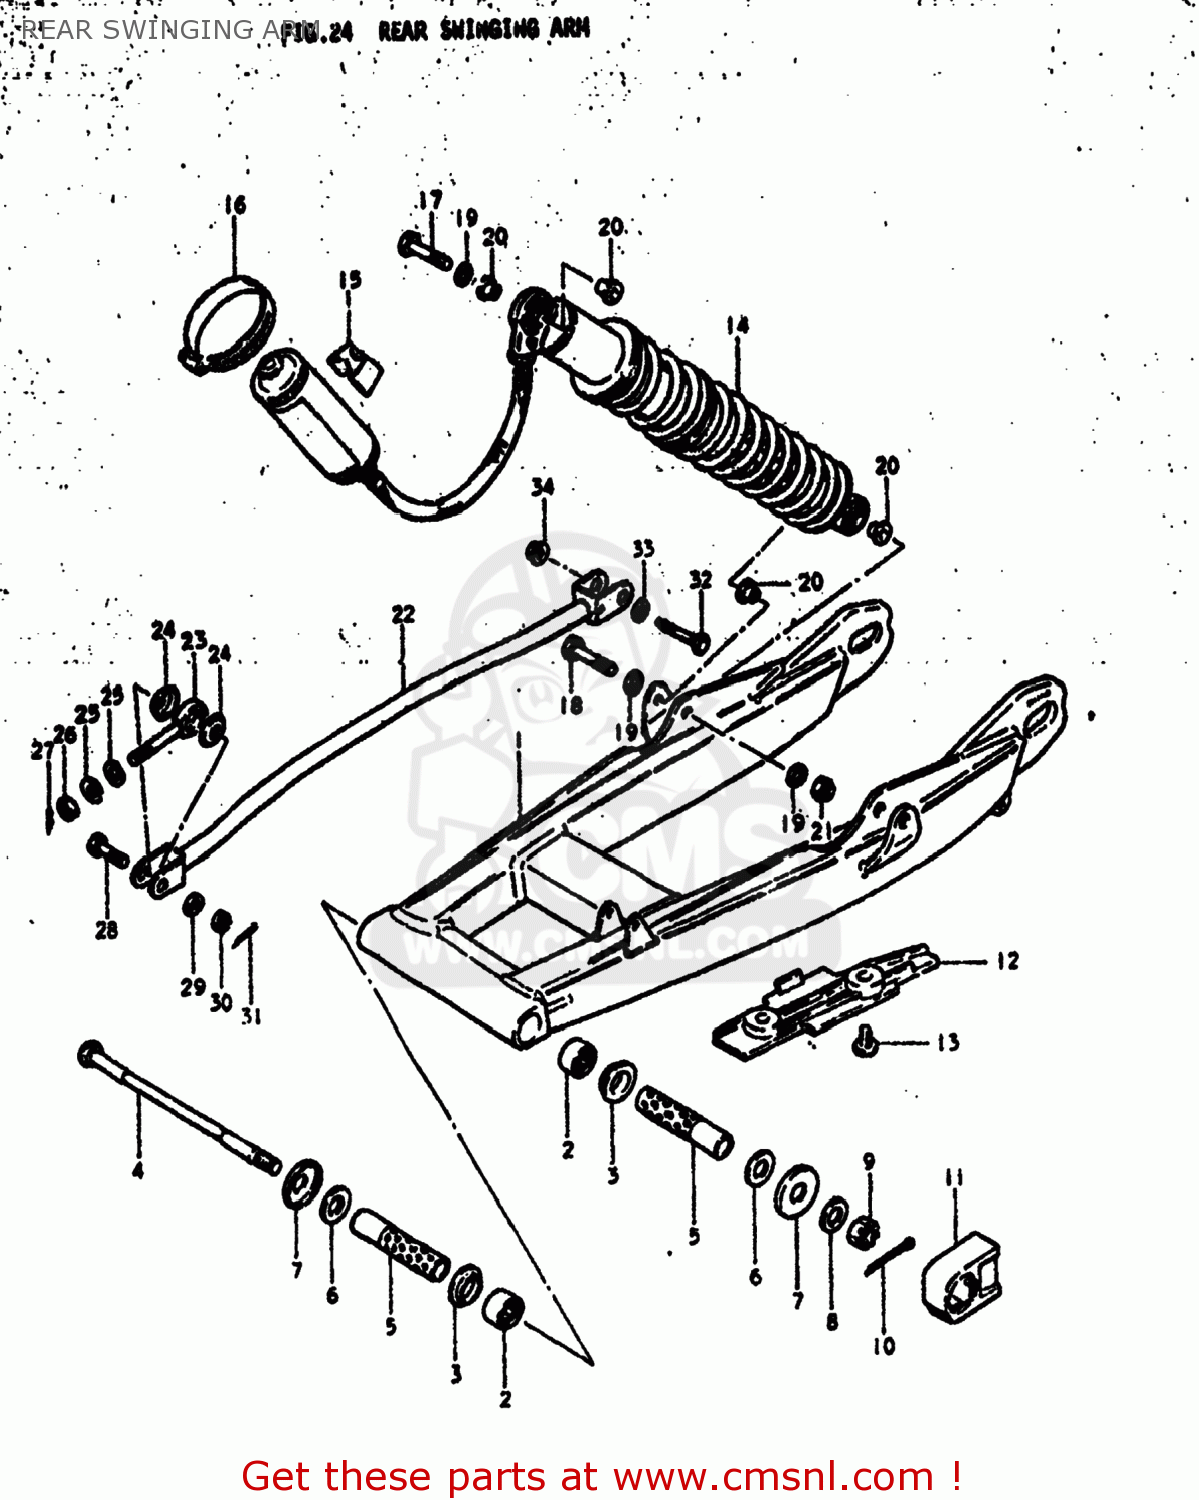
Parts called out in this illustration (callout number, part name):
1	SWING ARM ASSEMBLY,REAR
2	BEARING
3	BUSHING,REAR SWING ARM PIVOT
4	SHAFT,REAR SWING ARM
5	SPACER,REAR SWING ARM
6	WASHER
7	COVER,RR SWGARM DUST SEAL
8	WASHER
9	NUT 14MM
10	COTTER PIN
11	BUFFER,CHAIN TOUCH DEFLECTOR
12	BUFFER,CHAIN TOUCH DEFLECTOR
13	SCREW
14	ABSORBER ASSEMBLY,REAR SHOCK
15	CUSHION,RR SHOCK ABSORBER
16	CLAMP
17	BOLT
18	BOLT(8X46)
19	WASHER
20	SPACER,RR SHK ABS INNER
21	NUT
22	LINK,REAR TORQUE
23	BEARING
24	DUST SEAL,TORQUE LINK FR BRG
25	WASHER
26	NUT
27	CLIP
28	BOLT 8X28
29	WASHER
30	NUT 8MM
31	PIN 20X20
32	BOLT 10X40
33	WASHER
34	NUT
